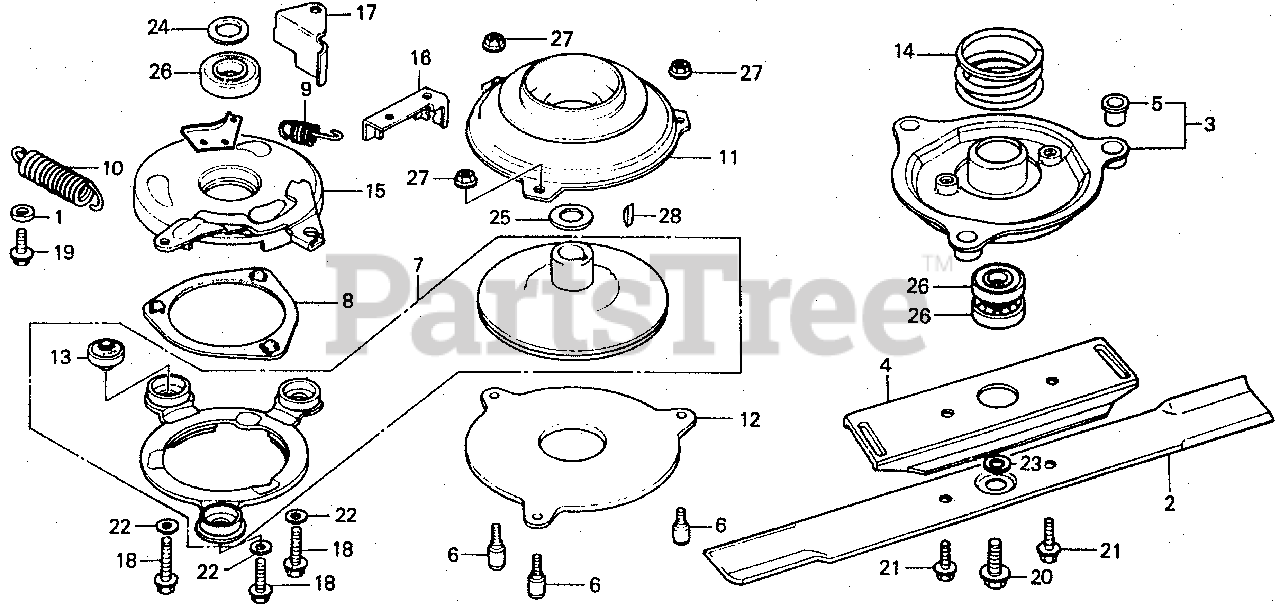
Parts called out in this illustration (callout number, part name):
1	COLLAR, FAN
2	BLADE, ROTARY
2	BLADE, ROTARY (21")
3	HOLDER ASSY., BLADE
4	HOLDER, BLADE
5	BUSH, BLADE HOLDER
6	PIN, DRIVE
7	DISK SET, BRAKE & CLUTCH (NOT AVAILABLE)
8	RETAINER, BALL
9	SPRING, ROTO-STOP CLUTCH RETURN (NOT AVAILABLE)
10	SPRING, ROTO-STOP CLUTCH RETURN
11	PULLEY, DRIVE (NOT AVAILABLE)
12	DISK, DRIVEN
13	RUBBER, DAMPER (NOT AVAILABLE)
14	SPRING, CLUTCH
15	PLATE, BALL CONTROL (NOT AVAILABLE)
16	PLATE, CABLE HOOK (NOT AVAILABLE)
18	BOLT, FLANGE (6X32)
19	BOLT, FLANGE (6X16)
20	BOLT, FLANGE UNF (3/8-24)
21	BOLT, HEX. (10X25)
22	WASHER (6MM)
23	WASHER (10MM)
24	WASHER, THRUST (22X32X3)
25	WASHER, THRUST (22X32X0.5)
26	BEARING, RADIAL BALL (60/22UU)
27	NUT, FLANGE (8MM)
28	KEY, WOODRUFF (16X15)
